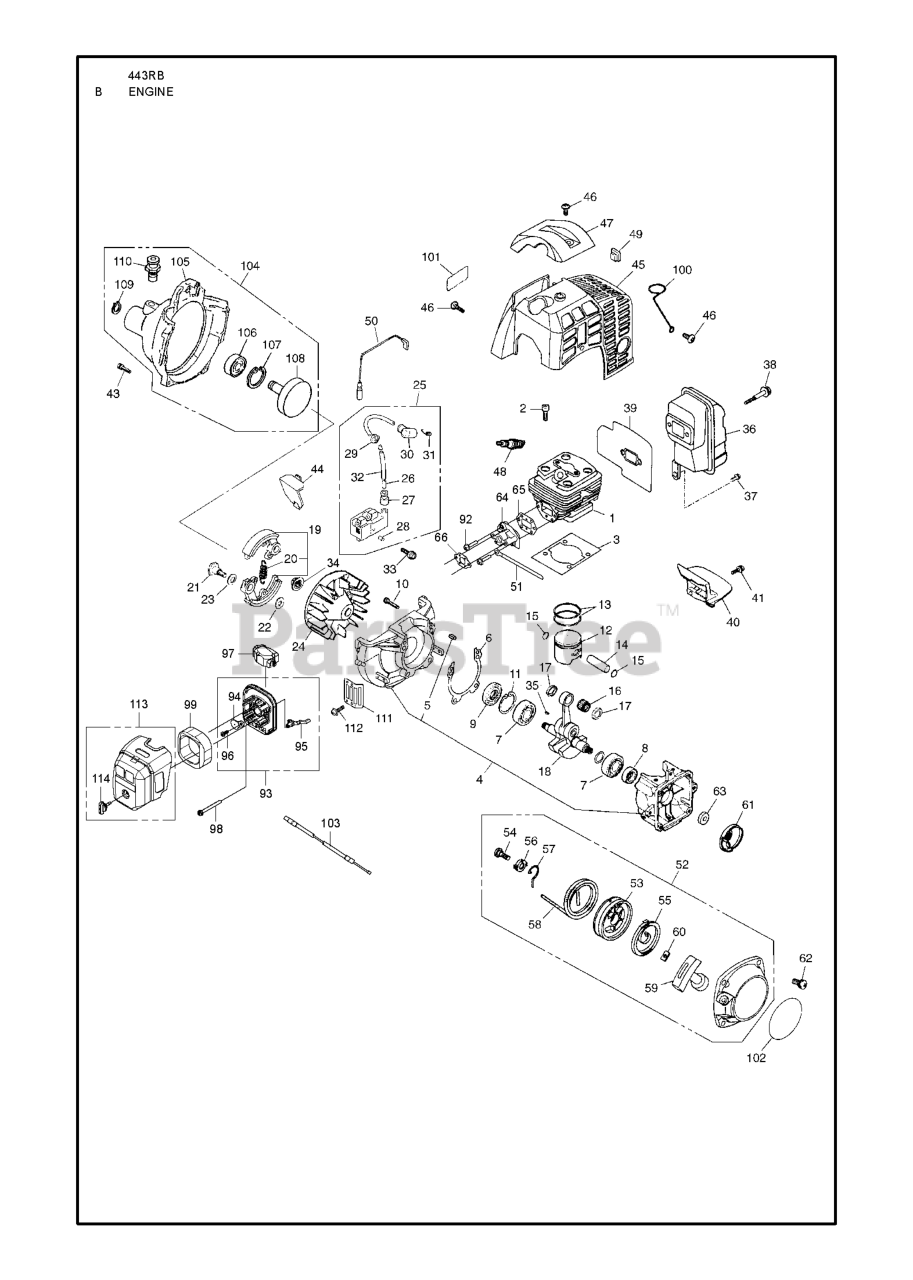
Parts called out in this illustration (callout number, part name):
13	RING, PISTON 2/PK
16	ROLLER BEARING
18	CRANKSHAFT COMPL
27	CAP
29	GROMMET
32	TUBE (RPLS 263072210)
34	NUT
40	PLATE.MUFFLER
48	SPARK PLUG RCJ6Y NLA
52	RECOIL ASSY
55	SPRING, SPIRAL
93	BODY ASSY.
94	PLATE, CHOKE
95	LEVER.CHOKE
96	SCREW
